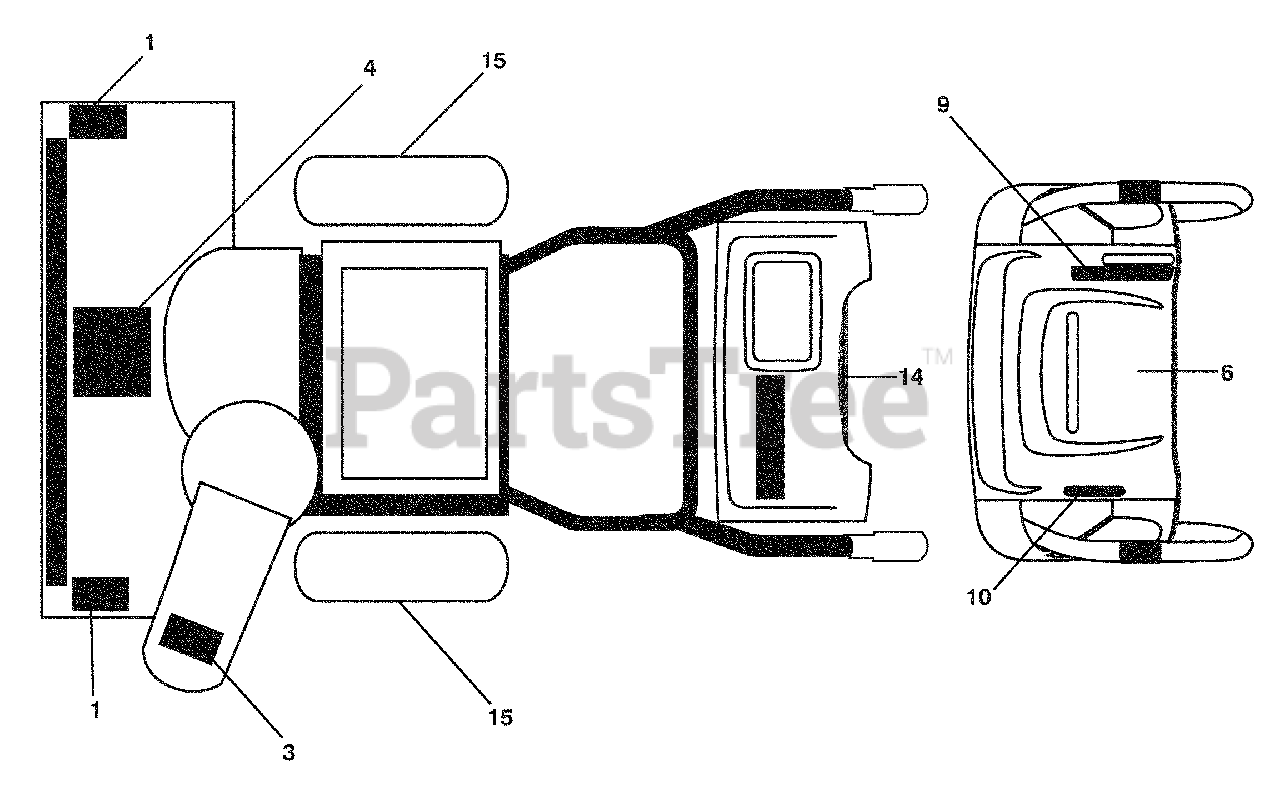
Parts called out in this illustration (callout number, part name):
1	DECAL, DANGER
3	DECAL, DANGER, DEFLECTOR
4	DECAL, DANGER
6	DECAL, INSTRUCTION
14	DECAL, SOUND LEVEL
15	DECAL, BELT GUARD
